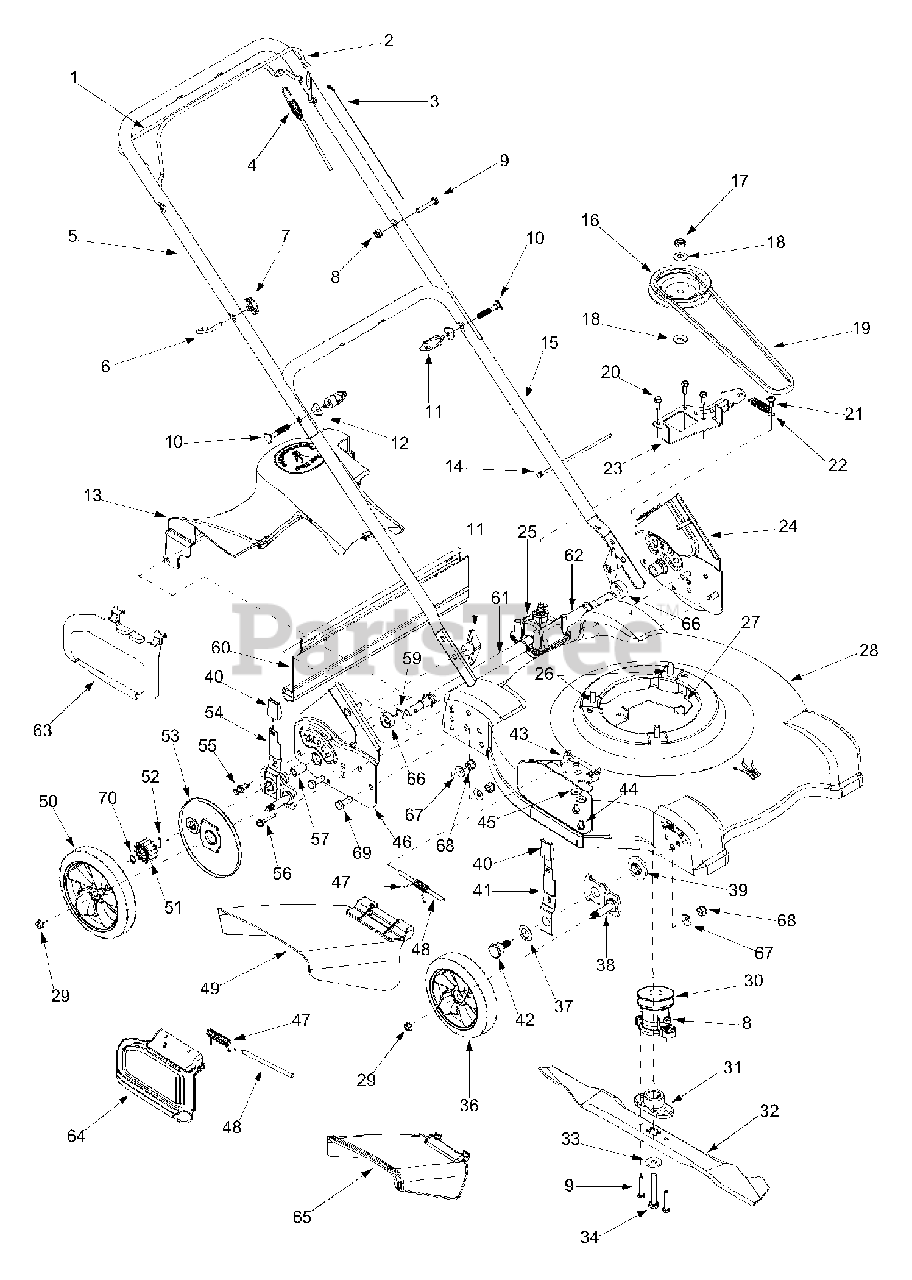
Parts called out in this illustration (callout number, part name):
1	Drive Control Handle
3	Blade Control Cable - B&S (37.75")
3	Blade Control Cable - B&S (40.75")
3	Blade Control Cable - Tec (50")
4	Drive Control Cable
6	Eye Bolt
7	Wing Nut 1/4-20
8	Hex Lock Nut 1/4-20
9	Hex Cap Screw 1/4-20 x 1.5
10	Carriage Bolt 5/16-18 x 2.0
11	Wing Nut 5/16-18
12	Shoulder Washer .320 ID x .93 OD
13	Transmission Cover
14	Cable Tie
16	Transmission Pulley
17	Jam Nut 7/16-20
18	Bell Washer .45 ID x 1.00 OD
19	V-Belt
20	Hex Washer Screw 1/4-20 x .75
21	Shoulder Screw .375 x .25
22	Extension Spring
23	Transmission Belt Bracket
26	Hex Washer Screw 3/8-16 x 1.0
27	Engine Belt Keeper Bracket
30	Engine Pulley
31	Blade Adapter
32	Blade 22"
32	Mulching Blade 22"
33	Bell Washer .396 ID x 1.140 OD
34	Hex Cap Screw 3/8-24 x 2.5
35	Shoulder Screw 3/8
36	Front Wheel 7 x 1.8
37	Bell Washer .401 ID x .870 OD
38	Pivot Arm Assembly
39	Height Adjuster Bearing
40	Height Knob
41	Spring Lever
42	Shoulder Screw 3/8-16
43	Chute Hinge
44	Hex Washer Screw 1/4-20 x .50
45	Bell Washer .265 ID x .75 OD
48	Hinge Pin
49	Side Discharge Assembly
50	Rear Wheel 8 x 1.8
51	Spur Gear 14T RH
51	Spur Gear 14T LH
52	Pin
53	Wheel Cover
54	Spring Lever Assembly - RH* (RWD)
54	Spring Lever Assembly - LH* (RWD)
55	Plastic Rivet
56	Screw 1/4-20
57	Sleeve Bearing
58	Hex Cap Screw 3/8-16 x .75
59	Retainer Ring
60	Trail Shield
61	Sleeve Spacer .550 ID x 9.0 OD
62	Sleeve Spacer .550 ID x 2.44 OD
63	Snap Mulching Plug
64	Mulching Baffle
65	Snap Discharge Chute
66	Bearing Spacer
67	Washer Spacer .401 ID x .870 OD
68	Hex Lock Nut 3/8-16
69	Hex Cap Screw 3/8-16 x 1.0
70	Snap Ring .500
